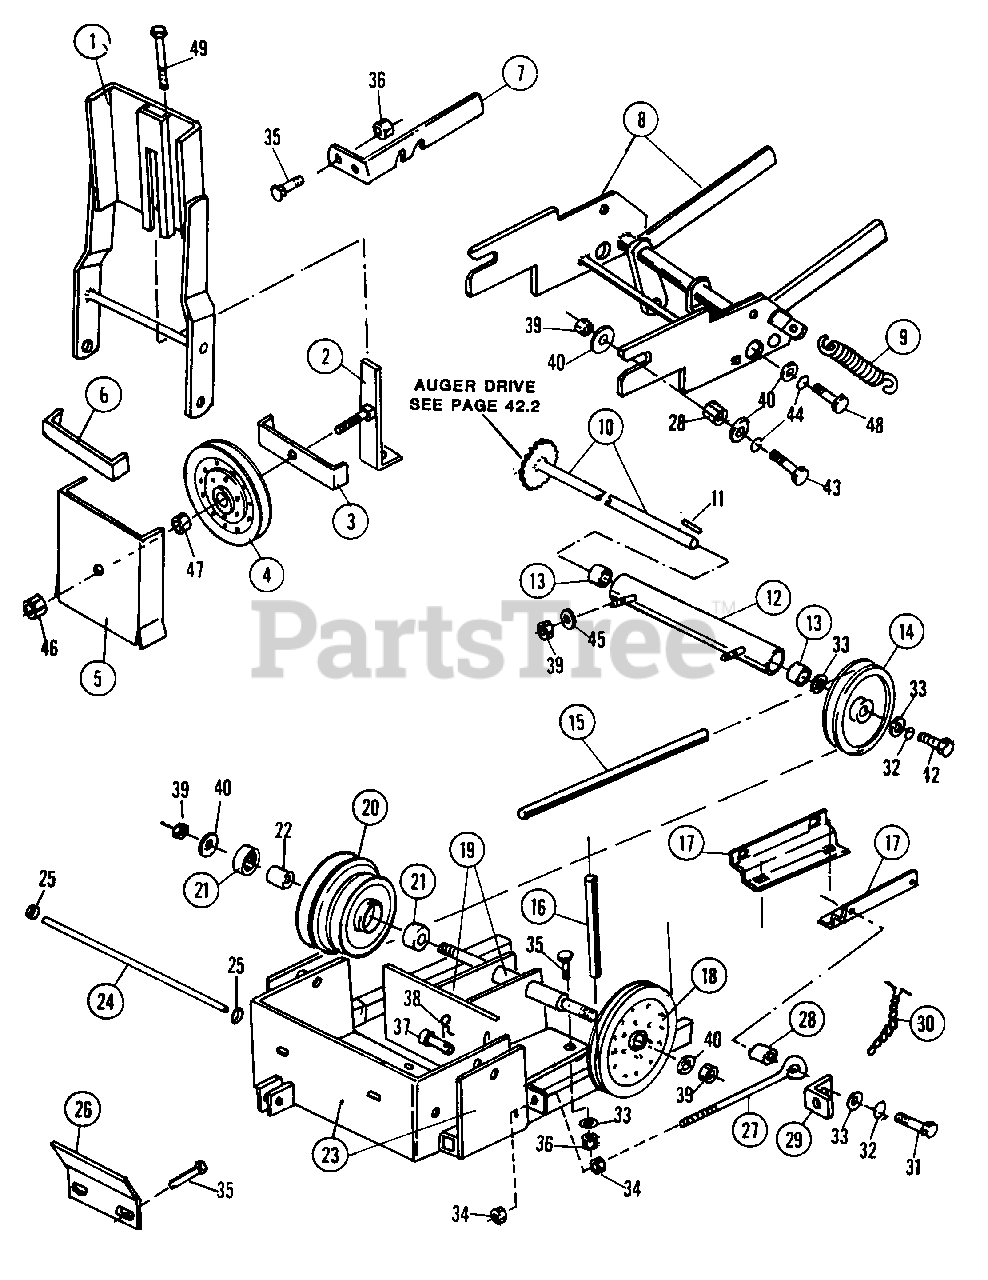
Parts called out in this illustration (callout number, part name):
1	BRACKET, IDLER PULLEY MOUNTING
2	BAR, IDLER PULLEY MOUNTING
3	BAR, PULLEY SUPPORT
4	PULLEY, IDLER (UPPER)
5	COVER, IDLER PULLEY
6	MOLDING, RUBBER
7	STRAP, IDLER RELEASE STOP
8	BRACKET, FRONT MOUNTING
9	SPRING, LIFT ASSIST
10	SPROCKET JACKSHAFT
11	KEY, 3/16 SQUARE x 1"
12	HOUSING, JACKSHAFT
13	BEARING, NEEDLE
14	PULLEY, JACKSHAFT DRIVE
15	BELT, DRIVE
16	BELT, IDLER
17	BRACKET, CHANNEL
18	PULLEY, IDLER (LOWER-RIVETED)
19	BRACKET, PULLEY MOUNTING
20	PULLEY, DRIVE BELT
21	BEARING, PULLEY
22	SPACER, BEARING
23	FRAME, DRIVE
24	ROD, BELT POPPER
25	CLIP, SPRING
26	PLATE, FRAME SUPPORT
27	EYE-BOLT
28	SPACER
29	BRACKET, CHAIN ANCHOR
30	CHAIN, ANCHOR TOGGLE
31	BOLT, 3/8-16x2 HEX HEAD
32	LOCKWASHER, 3/8"
33	WASHER, 3/8" Flat
34	NUT, 1/2 HALF HEX
35	BOLT, 3/8-16 CARRIAGE
36	LOCKNUT, 3/8 HEX
37	CLEVIS-PIN, 5/8x1-7/8
38	HAIR-PIN
39	LOCKNUT, 1/2-13 HEX
40	WASHER, 17/32x1-1/16x3/32
42	BOLT, 3/8x3/4 HEX HEAD
43	BOLT, 1/2-13x1-1/2 HEX HEAD
44	LOCKWASHER, 1/2"
45	WASHER, 1/2x1-1/4x5/64
46	NUT, 5/8 HALF HEX
47	NUT, 5/8 C HEX
48	BOLT, 1/2-13 x 1-1/4 HEX HEAD
49	BOLT, 1/2c SPECIAL BELT ADJUSTING
